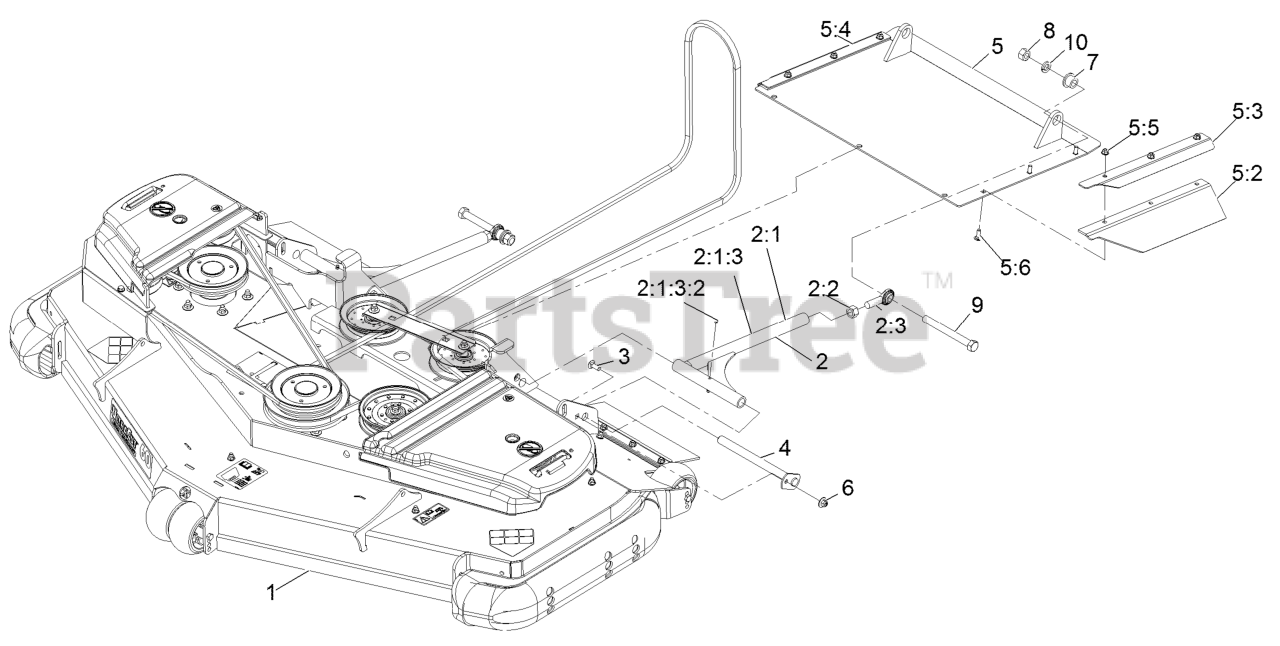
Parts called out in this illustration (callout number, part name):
1	ASM-Deck Complete Rd60
2	ASM,DECK STRUT XS 60
2:1	STRUT-DECK
2:1:3	Tube And Zerk ASM
2:2	NUT-HEX
2:3	BALLJOINT-SPHERICAL
3	BOLT-CARR
4	PIN-STRUT
5	ASM-DISCHARGE TUNNEL RD60
5:2	FLAP-RD TUNNEL SIDE
5:3	BRKT-RD TUNNEL FLAP LH
5:4	BRKT-RD TUNNEL FLAP RH
5:5	NUT-HF, NI
5:6	SCREW-CARR
6	Nut-Nyloc 3/8-16 Flg
7	BUSHING-FLANGE
8	NUT-HEX
10	WASHER-LOCK
